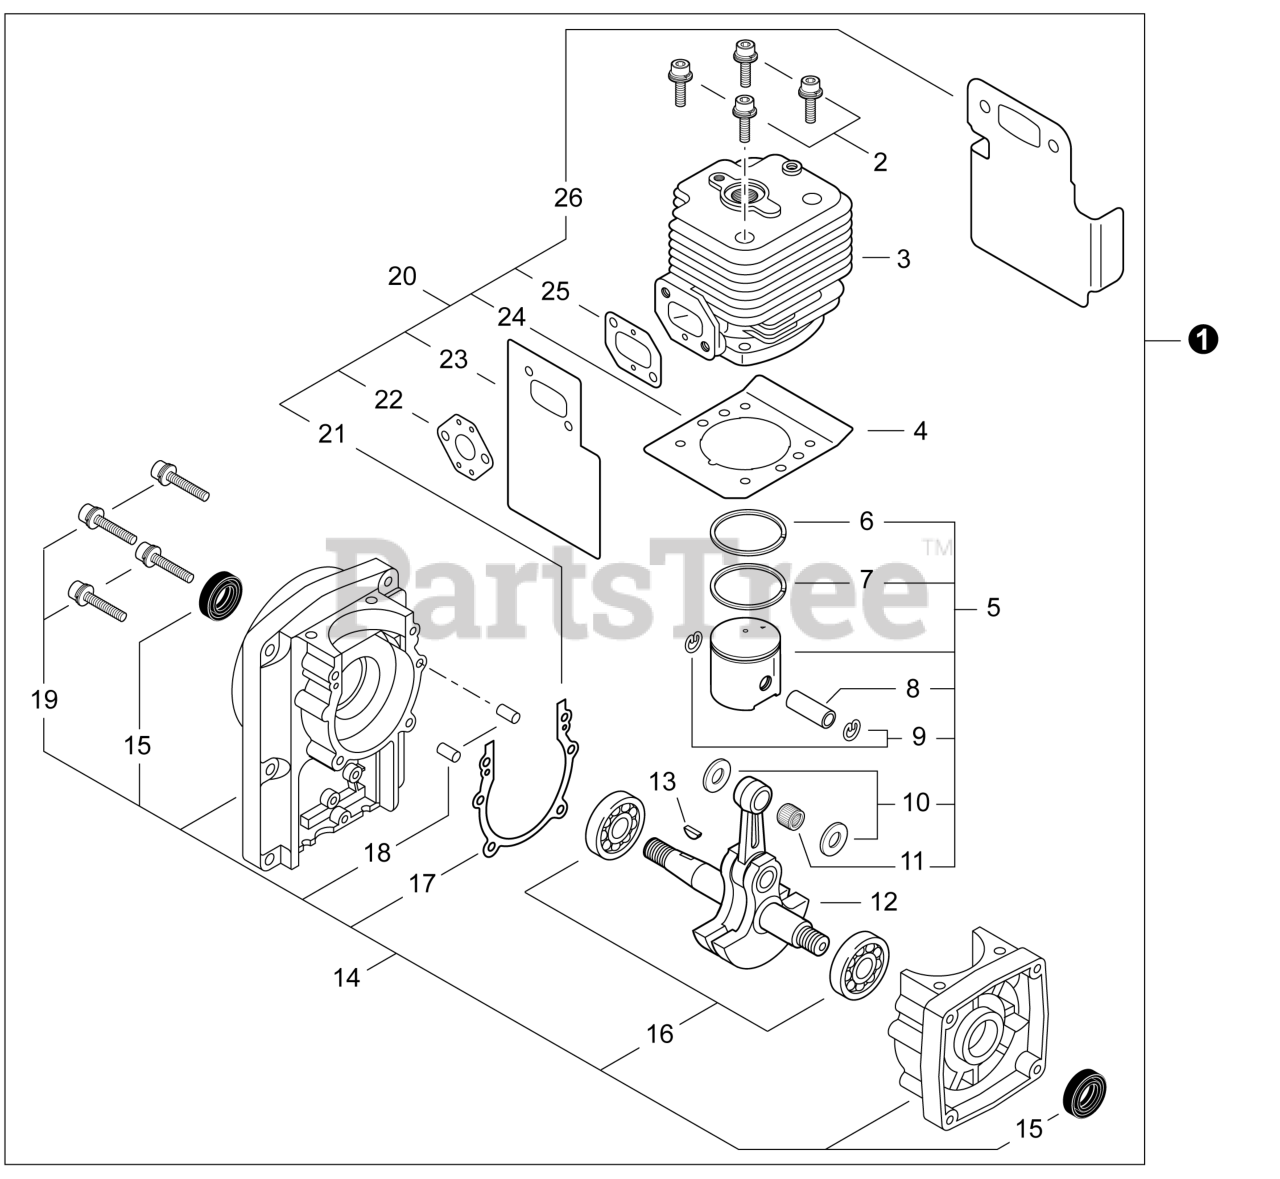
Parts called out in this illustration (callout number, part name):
1	SHORT BLOCK
2	BOLT 5×25
3	CYLINDER
4	GASKET, CYLINDER
5	PISTON KIT
6	RING, PISTON
7	RING, PISTON
8	PIN, PISTON
9	RING, SNAP 8
10	WASHER, THRUST
11	BEARING, NEEDLE 10
12	CRANKSHAFT ASSY
13	KEY, WOODRUFF 3×14
14	CRANKCASE KIT
15	SEAL, OIL 15
16	BEARING, BALL 6302
17	GASKET, CRANKCASE
18	PIN, LOCATING 4×8
19	BOLT M5×35
20	GASKET KIT
21	GASKET, CRANKCASE
22	GASKET, INTAKE
23	HEAT SHIELD, INTAKE
24	GASKET, CYLINDER
25	GASKET, INTAKE
26	HEAT SHIELD, EXHAUST
